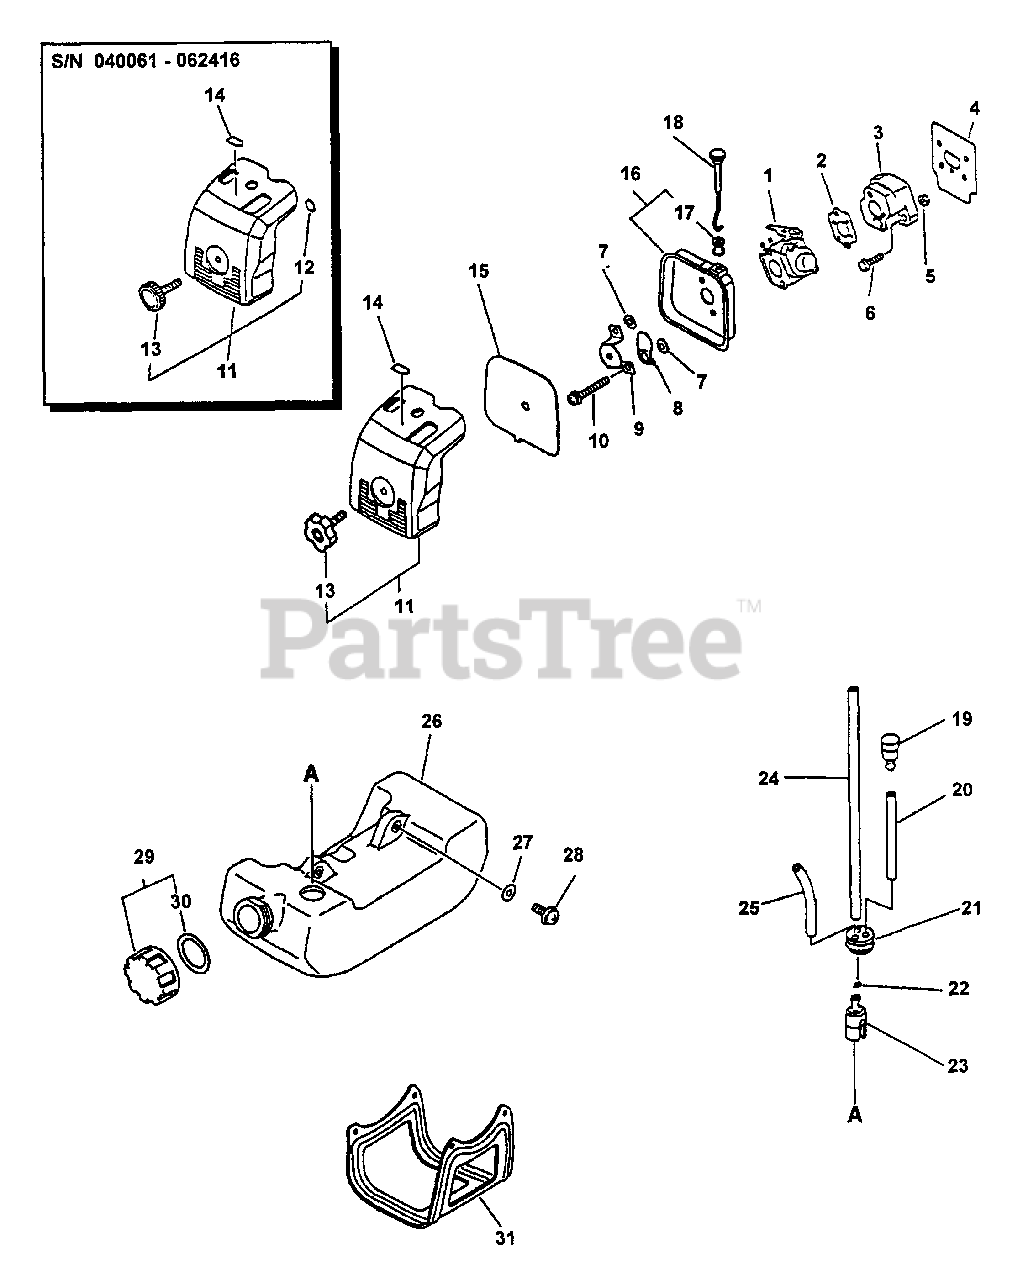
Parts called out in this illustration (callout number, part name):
1	CARBURETOR C1U-K23A
1	CARBURETOR WT-424A
2	GASKET, INTAKE
3	INSULATOR, INTAKE
4	SHIELD, INTAKE
6	SCREW - 5X20
7	WASHER - 5
8	SHUTTER, CHOKE
9	PLATE, PREVENT
10	SCREW - 5X57
11	AIR FILTER COVER ASSY
12	O-RING - 3
13	THUMBSCREW
14	LABEL - CHOKE
15	FILTER, AIR - HEAVY DUTY
16	CASE, AIR FILTER
18	ROD, CHOKE
19	VENT, FUEL TANK
20	PIPE - 3X5X70 -- BLACK
21	GROMMET
22	CLIP - 6
23	FILTER, FUEL
24	PIPE - 3X5X180 -- BLACK
25	PIPE - 3X6X90 -- CLEAR
26	TANK, FUEL
27	WASHER - 5
28	SCREW - 5X16
29	CAP ASSY
30	GASKET, CAP
31	GUARD, FUEL TANK
